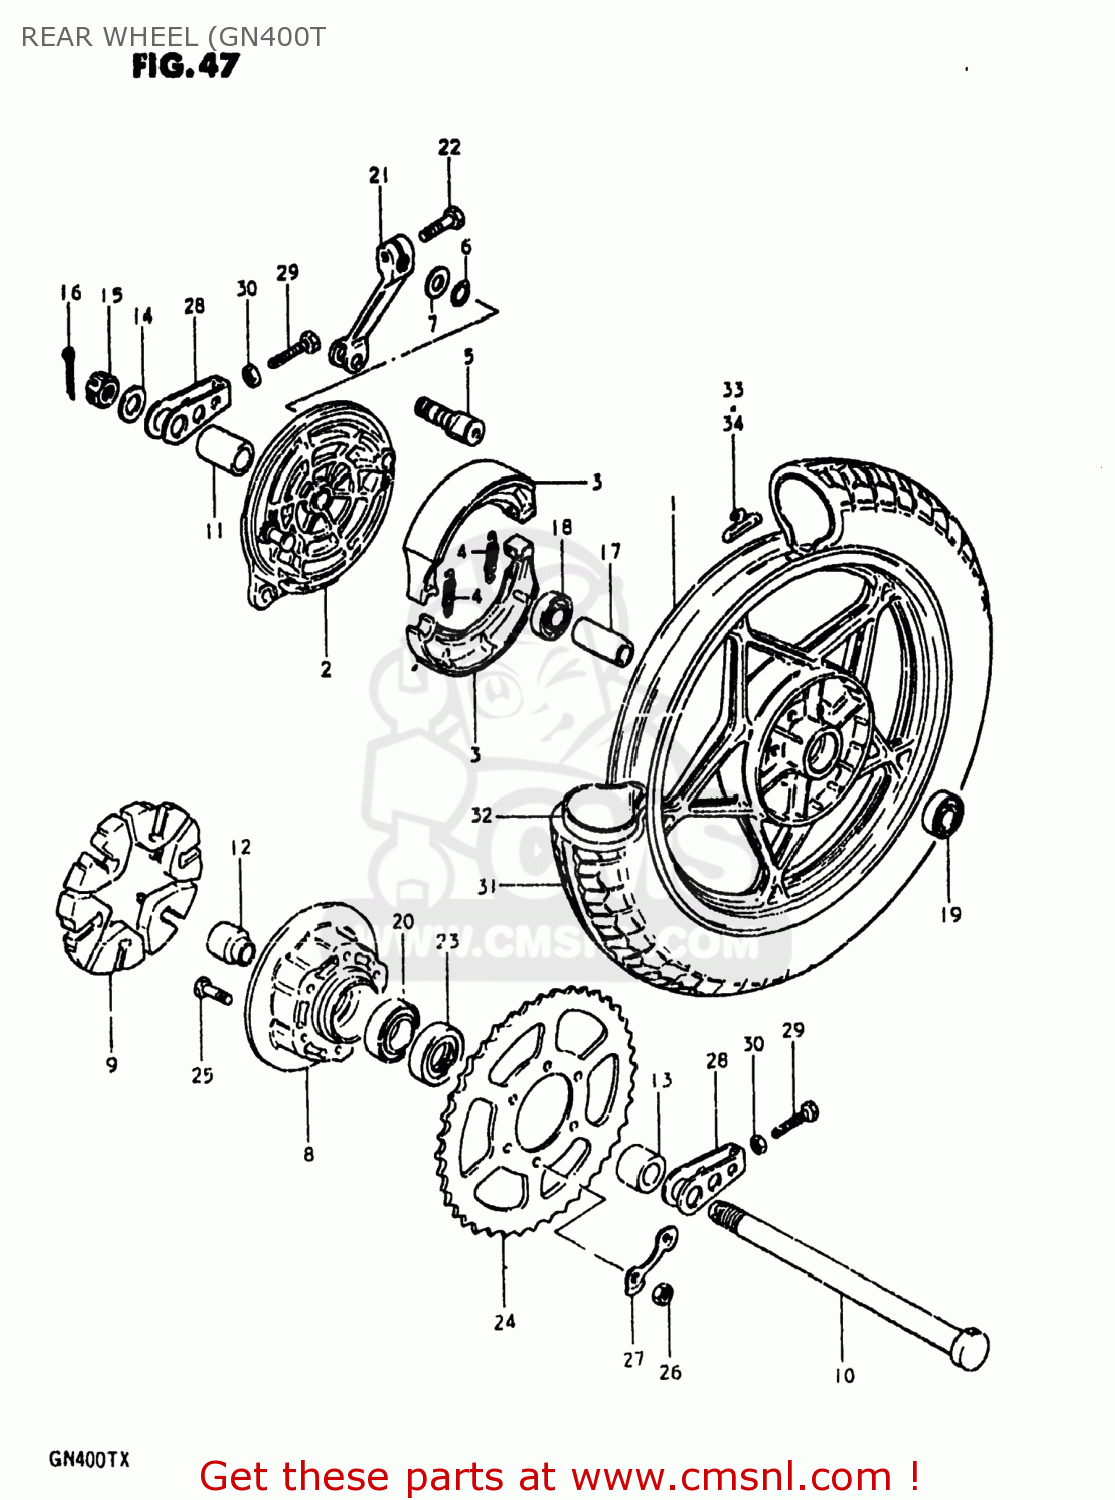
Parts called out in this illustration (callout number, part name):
1	WHEEL,REAR
2	PANEL,REAR HUB
3	SHOE,BRAKE
4	SPRING
5	CAM,FRONT BRAKE
6	O-RING,BOSS
7	WASHER (15X24X1.6)
8	DRUM,REAR SPROCKET MOUNT
9	ABSORBER,RR HUB SHOCK
10	AXLE,REAR
11	SPACER (17.5X28X49.8)
12	SPACER,REAR HUB BEARING
13	SPACER(17X30.5X22.3)
14	WASHER (17X30X3.2)
15	NUT
16	PIN,COTTER
17	SPACER (17.6X24X57)
18	BEARING
19	BEARING
20	BEARING
21	LEVER,RR BRAKE CAM
22	BOLT
23	SEAL,OIL(30.5X52X8)
24	SPROCKET,REAR (NT:37)
25	BOLT
26	NUT
27	WASHER
28	ADJUSTER,CHAIN
29	BOLT 8X50
30	NUT
31	TIRE
32	TUBE ASSY,WHEEL,INNER 4.60-16
33	BALANCER,WHEEL
34	BALANCER,WHEEL
